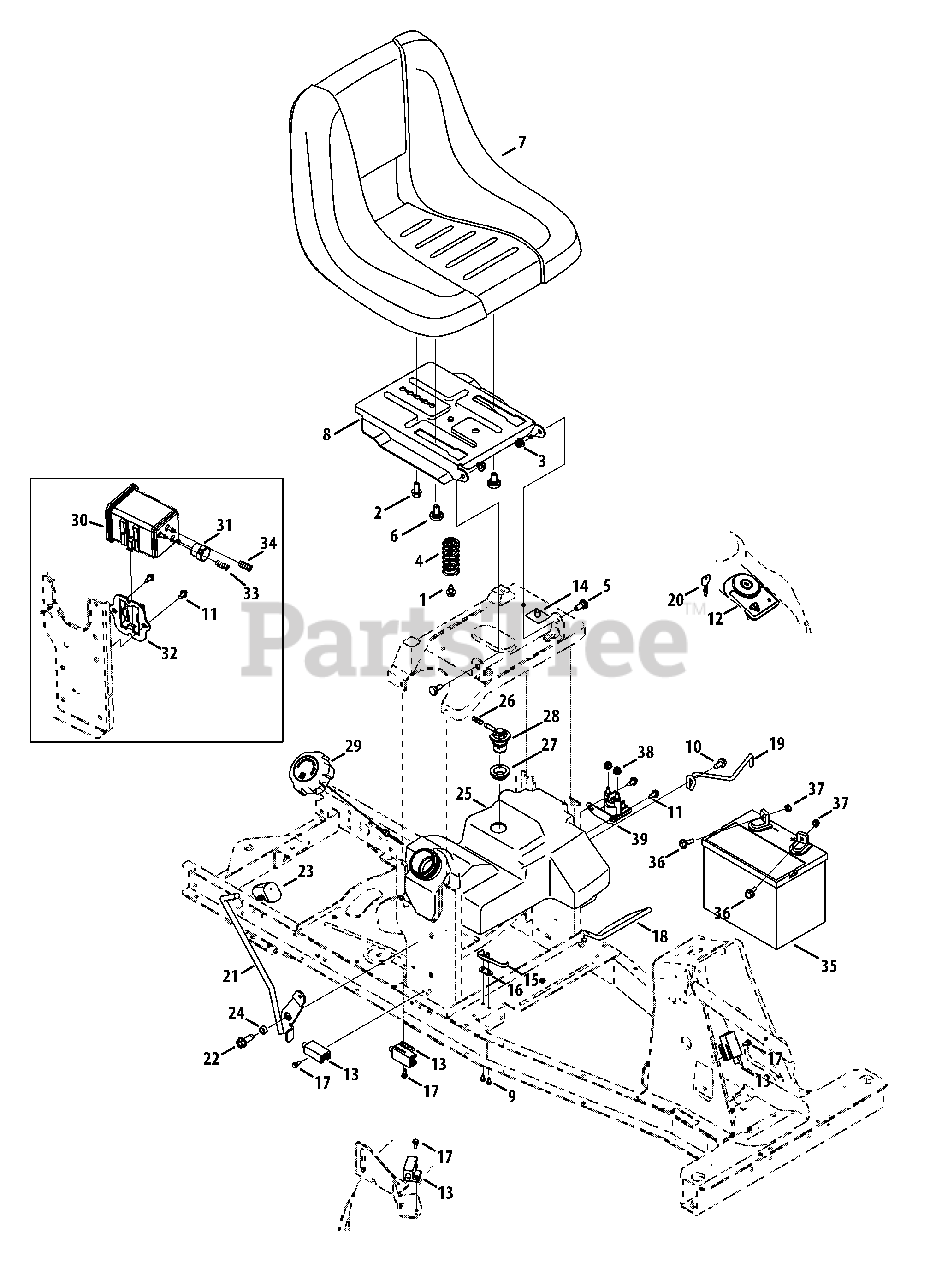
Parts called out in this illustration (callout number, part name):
1	Tap Screw, 5/16-18, 0.500
2	Hex Flange Screw, 3/8-16 x .75
3	Flange Lock Nut, 5/16-18
4	Seat Spring
5	Shldr Spacer, .435 X .178-5/16 X .56
6	Shoulder Screw, .625 x .145, 3/8-16
8	Seat Pivot Bracket
9	Screw, #8
10	Tap Screw, 5/16-18, .750
11	Tap Screw, 1/4-20, .625
12	Key Switch
13	Interlock Switch
14	Seat Switch
15	Switch Spring
16	Insulator Plate
17	Shoulder Screw, #10-32, .500
18	Battery Rod
19	Battery Hold Down Bracket
20	Key, Assembly
21	PTO Handle Assembly
22	Tap Screw, 3/8-16, 1.000
23	Handle Grip, 3/8
24	Spacer, .380 ID x .50 OD x .265
25	Fuel Tank, 1-3 Gal.
26	Hose Vent, 3/16 EPA
27	Rubber Grommet
28	Rollover Valve
29	Fuel Cap
29	Fuel Cap, Carb
30	5 GallonCarbon Canister
31	Vent Filter Canister
32	Canister Adapter Bracket
33	Fuel Hose, White
34	Fuel Hose, Yellow
35	Battery, 155 CCA
36	Screw, Shoulder, .250 x .150
37	Nut, Sems, 1/4-20
38	Flange Lock Nut, 1/4-20
39	Solienoid, 12v
